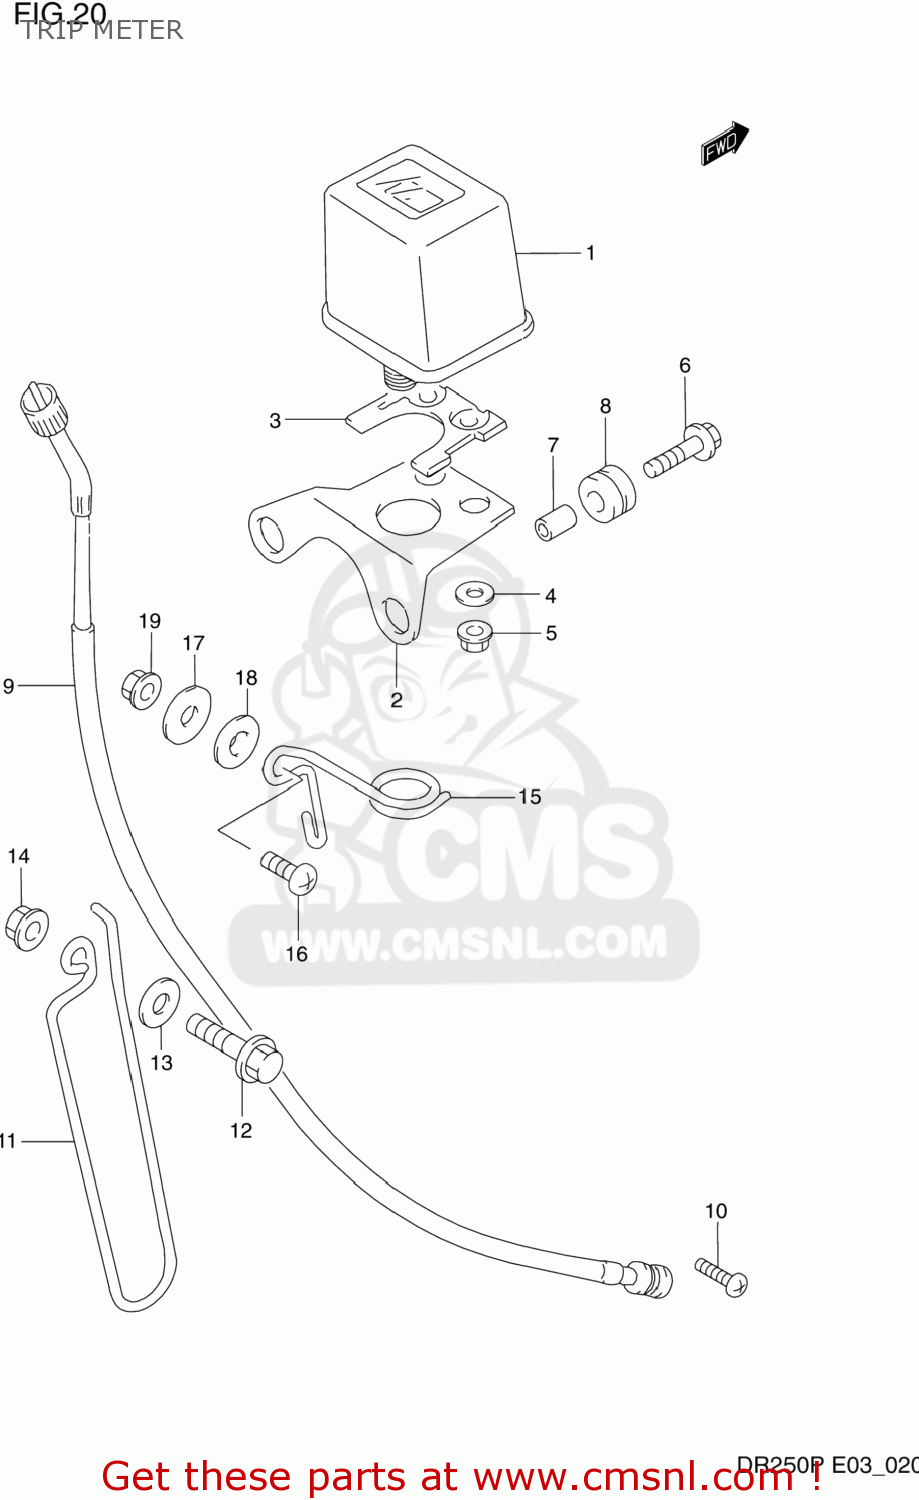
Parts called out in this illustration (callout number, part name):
1	TRIP METER
2	BRACKET
3	CUSHION
4	WASHER,METER
5	NUT
6	BOLT(6X25)
7	SPACER (6.1X8X9.5)
8	CUSHION
9	CABLE ASSEMBLY,SPEEDOMETER
10	SCREW
11	GUIDE,METER CABLE NO.2
12	BOLT 6X20
13	WASHER
14	NUT
15	GUIDE,METER CABLE NO.3
16	SCREW
17	WASHER
18	WASHER
19	NUT
